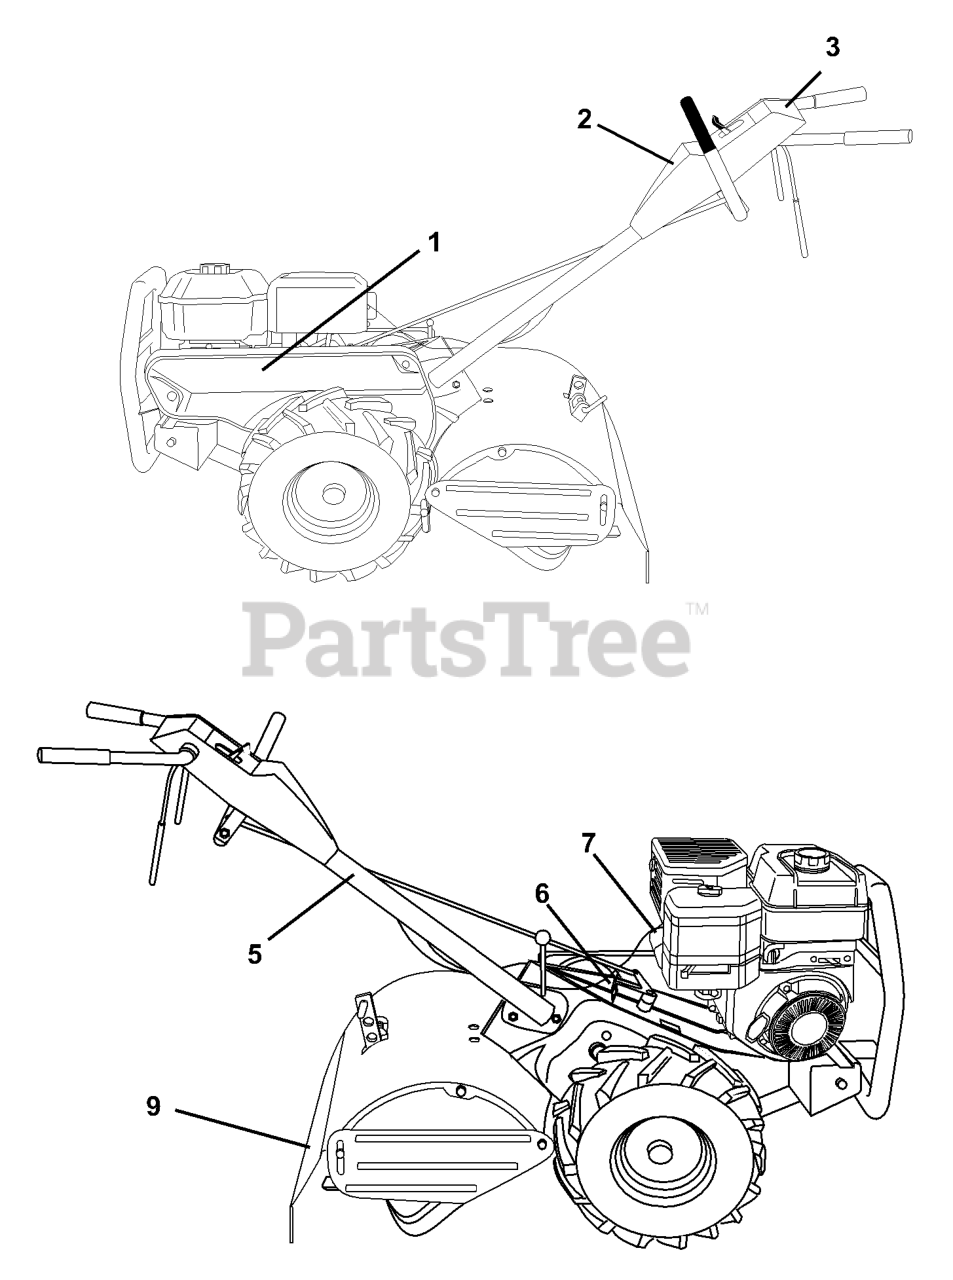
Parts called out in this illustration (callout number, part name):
1	DECAL-BELT GUARD
2	DECAL, LOGO
3	LOGO DECAL
5	DECAL TI (2 2)
6	DECAL.SHIFT.INDICATOR.TILLER
7	DECAL -CAUTION
9	DECAL TI
